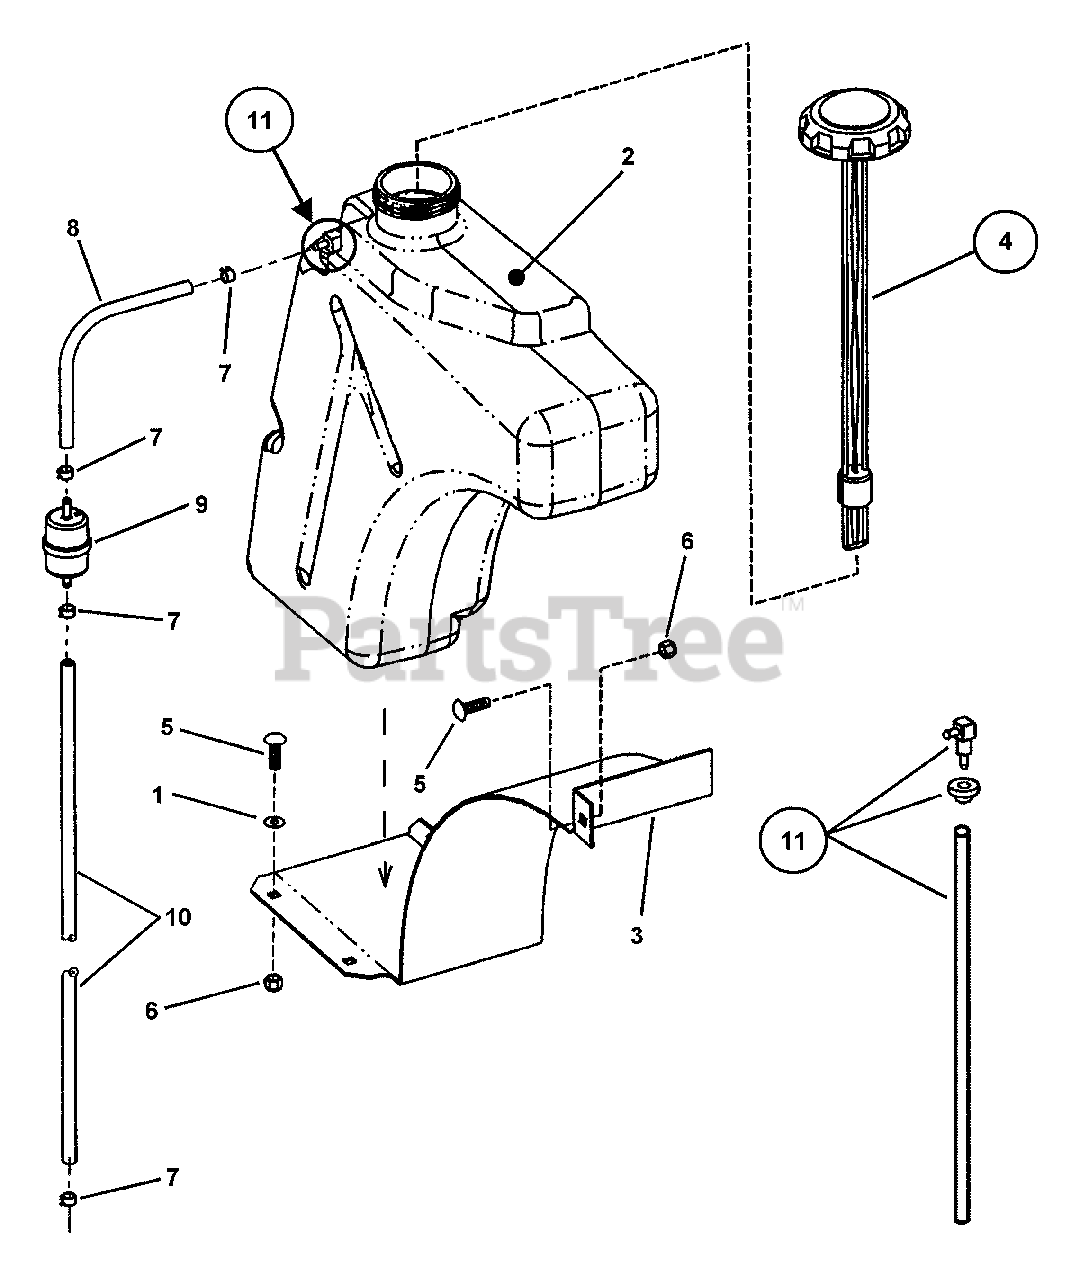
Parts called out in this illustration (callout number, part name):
1	RETAINER, 3/8 Bolt
2	TANK, Fuel
3	BRACKET, Fuel Tank Support
4	ASSEMBLY, Cap/Gauge
5	BOLT, 3/8-16 x 1" Square Neck Carriage, Grade 5
6	NUT, 3/8-16 HEX NYLON LOCK
7	CLAMP, Fuel Hose
8	HOSE, Fuel 1/4 x 4"
9	FILTER, Fuel
10	HOSE, Fuel 1/4 x 24"
11	ASSEMBLY, Fuel Suction Line
